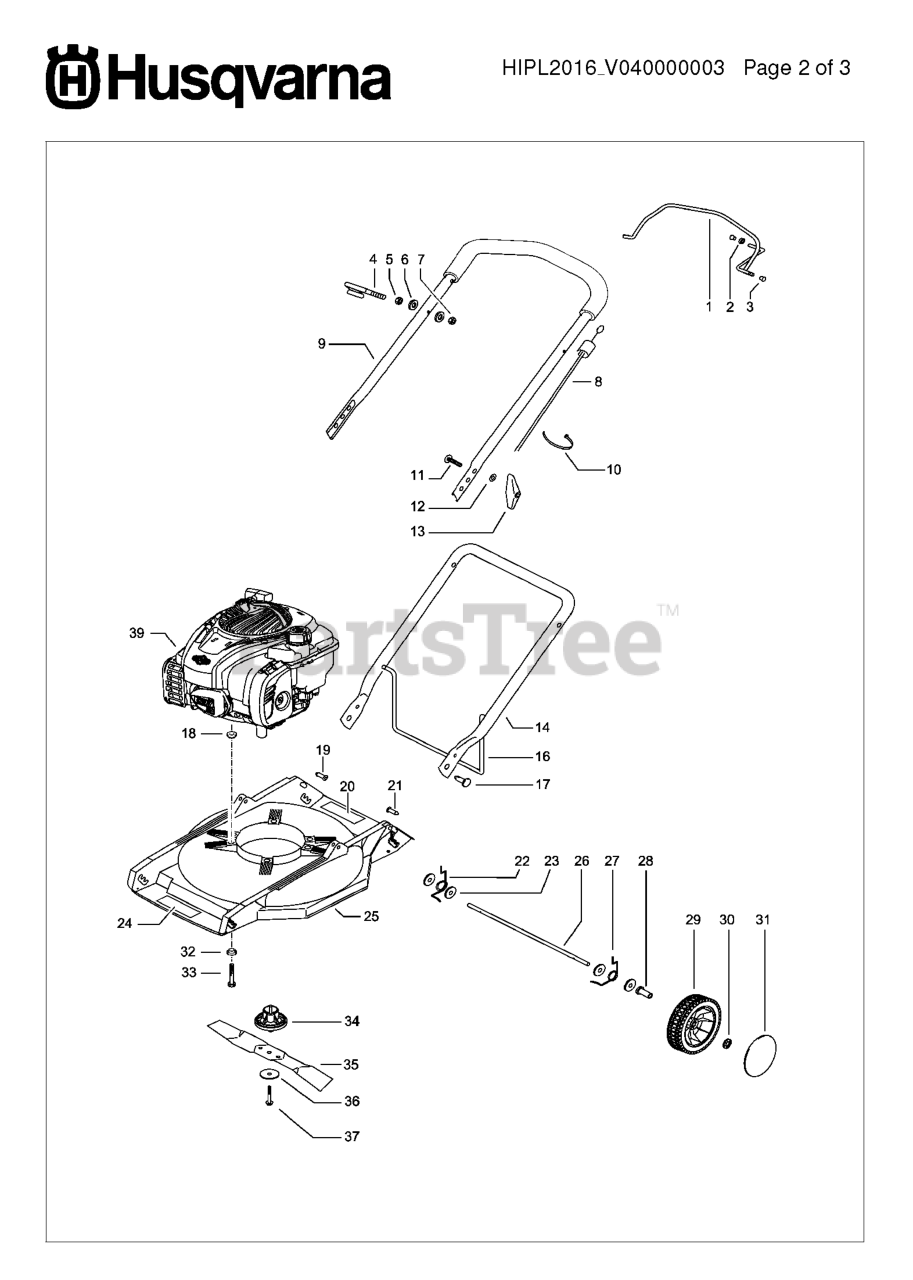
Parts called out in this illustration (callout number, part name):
1	STEERING WHEEL
2	AXLE ASSY FRONT
3	SPINDLE.ASM.LH.15"TIRES
4	SPINDLE.ASM.RH.15"TIRES
5	THRUST WASHER
10	DRAGLINK.15".TIRES.2001
11	WASHER, LOCK 3/8
12	NUT.HEX.1/2-20
13	TUBE, PIVOT AXLE
15	NUT
17	SHAFT ASM STRG
29	SCREW, 3/8-16X3/4
33	WASHER M
34	WASHER.LOCK.HVY.HLCL.SPR.5/16
35	NUT, CROWNLOCK
36	BUSHING STRG 3/4
37	SCREW.TT.#10-32X.5.3/8.FLANGE
38	INSERT.CAP.STRG.WH.GRAY
39	WASHER 9/16"ID, 2 3/8"OD
41	ADAPTER, WHEEL STNG..
46	CAP.SPINDLE
65	SPACER BRACE AXLE
67	BOLT CARRIAGE
68	BRACE.AXLE.15"TIRES
71	STEERING ASM
82	BRACKET.SUSP.CHASSIS.FRONT.15
87	WASHER, FLAT .781 X 1 1/2"
88	BOLT, SHOULDER 7/16-20
91	CLIP.STEERING
95	WASHER.HARDENED
